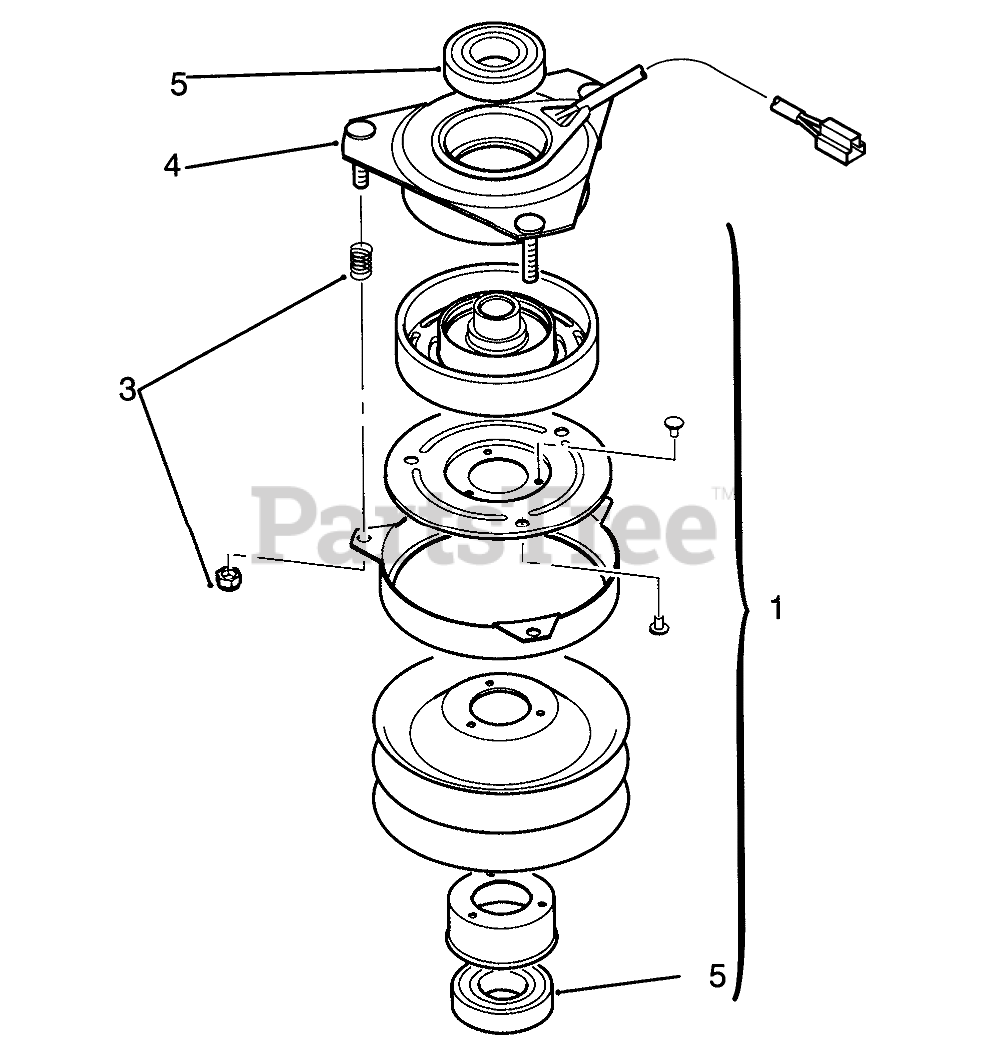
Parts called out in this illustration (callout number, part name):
1	Rotor & Armature Assembly (Incl. Ref. #5)
3	ACCESSORY PKG SRVC PART
4	Assembly-Field (Incl. Ref. #5)
5	BEARING-ELEC CLUTCH
